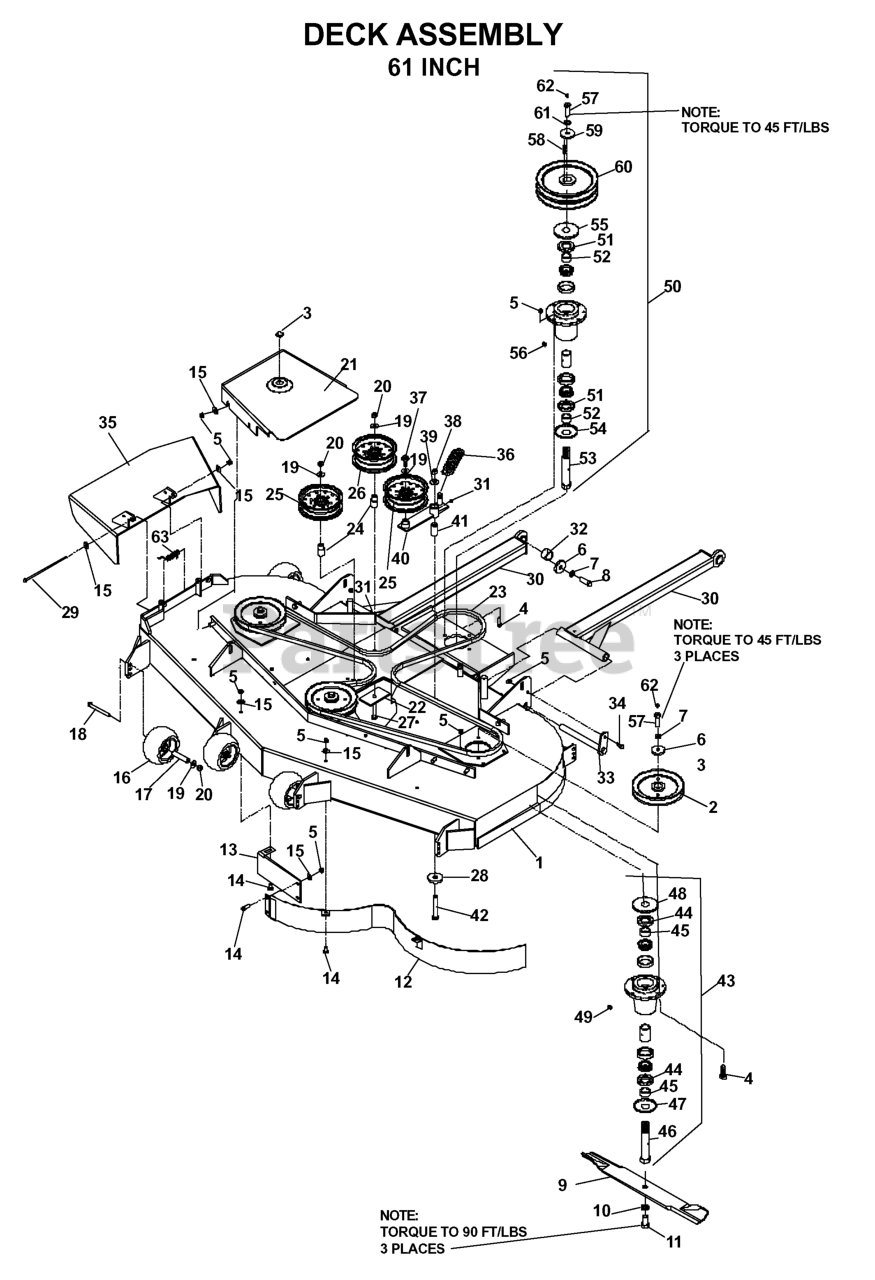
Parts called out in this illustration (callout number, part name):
1	DECK W/DECALS 61" HUS WSL
2	RP PULLEY - 61"
3	PLUG, BUTTON HOLE
4	HCS 5/16C X 1
5	NUT 5/16C CENTERLOCK
6	SPINDLE WASHER
7	WASHER 7/16 LOCK
8	HCS 7/16F X 1 1/2
9	BLADE OEM 21" (61" DECK)
10	LOCKWASHER 5/8
11	HCS 5/8F X 1 1/4
12	MAIN BAFFLE - 61" BLK
13	CENTER BAFFLE - 61
14	CARRIAGE BOLT 5/16C X 5/8"
15	WASHER 5/16 FLAT
16	ANTI-SCALP ROLLER
18	HCS 3/8C X 3 1/2
19	WASHER 3/8 FLAT
20	NUT 3/8C CENTERBLOCK
21	RT 61 CE SHIELD ORANGE
22	SUPPORT PLATE
23	BELT, DECK
24	IDLER BUSHING
25	IDLER PULLEY
26	IDLER PULLEY (TALL)
27	HCS 3/8C X 2 1/2
28	WASHER, SUPPORT
29	HCS 5/16-18 X 8-1/2 GR 5 ZD
30	STRUT WELDMT, L.H.
31	ZERK
32	SPACER, STRUT
33	PIN WELDMENT
34	HCS 5/16C X 3/4
35	CHUTE 61 ORANGE
36	DECK SPRING
37	4CS 3/8C X 1 SERRATED HEAD
38	NUT 1/2-13 HEX NYLOC ZD
39	WASHER 1/2 FLAT
41	PIVOT BUSHING
42	HCS 1/2C X 3 1/4
43	SPINDLE
44	SHAFT SEAL
46	52/61 SPINDLE - SPLINED SHAFT
47	BOTTOM DUST CAP
48	TOP DUST CAP
49	PLUG-VENTED
50	JACKSHAFT ASSY LOWER
51	SHAFT SEAL
53	JACKSHAFT SPINDLE
54	BOTTOM DUST CAP
55	TOP DUST CAP
56	PLUG-VENTED
57	HCS 7/16C X 1 1/2
58	KEY 1/4 SQ X 1 1/8
59	SPINDLE WASHER
60	SHEAVE WSL
61	WASHER 7/16 LOCK
62	ZERK
63	SPRING, TORTION
539108916	LT 61 CE SHIELD ORANGE
